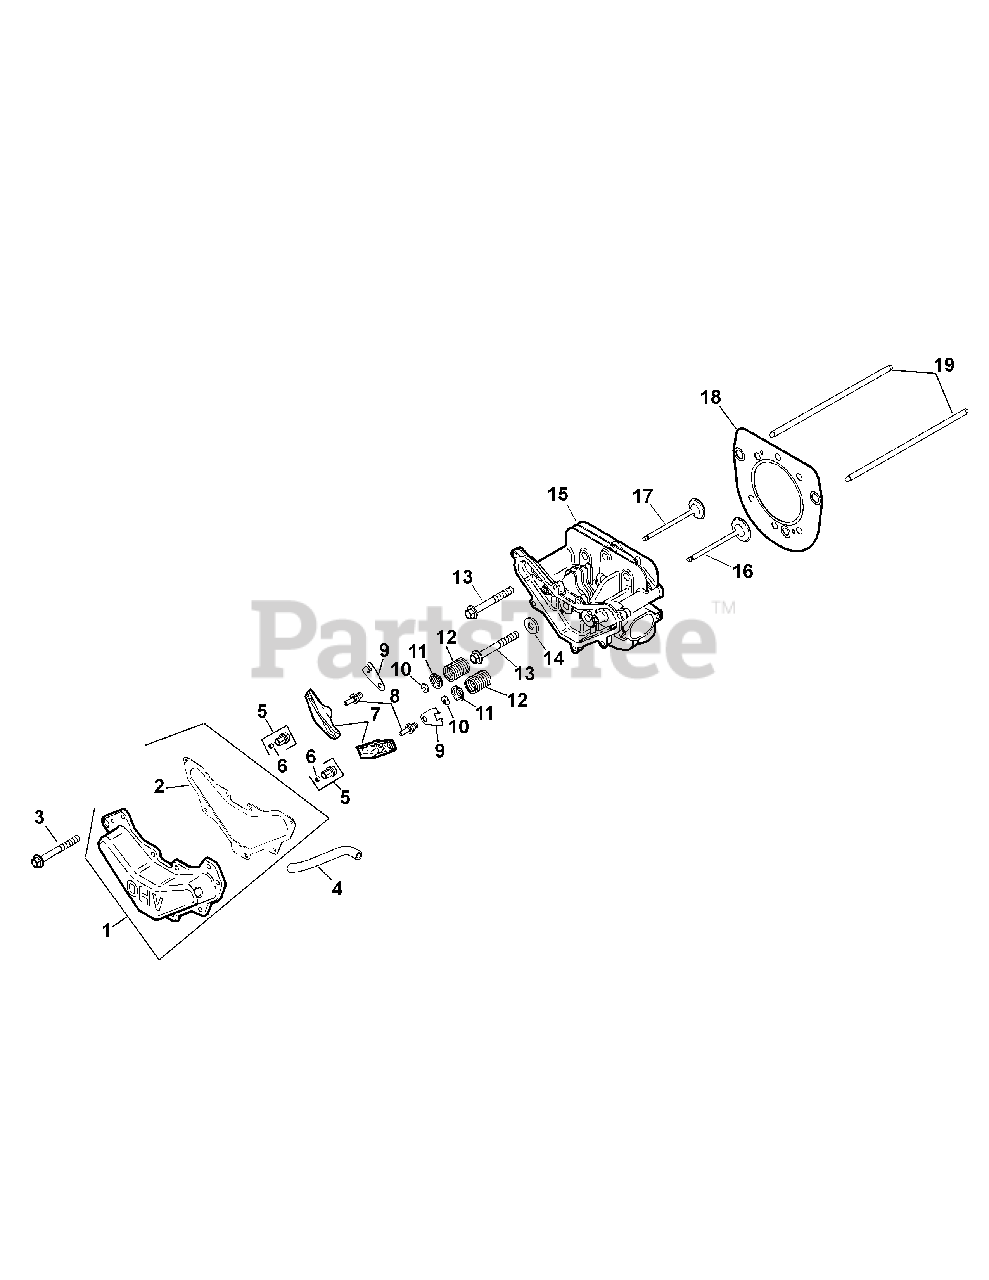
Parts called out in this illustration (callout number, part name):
1	Valve Cover Kit (Inc. 2)
2	Valve Cover Gasket
3	Hex Flange Screw, M6 x 1.0 x 20
4	Breather Hose
5	Rocker Arm Pivot Kit (Inc. 6)
8	Rocker Arm Stud
9	Push Rod Guide Plate
10	Valve Spring Retainer Lock
11	Valve Spring Cap
13	Hex Flange Screw, M10 x 1.5 x 80
14	Flat Washer, 13.32
15	Cylinder Head
16	Exhaust Valve
18	Cylinder Head Gasket Repair Kit
19	Push Rod
